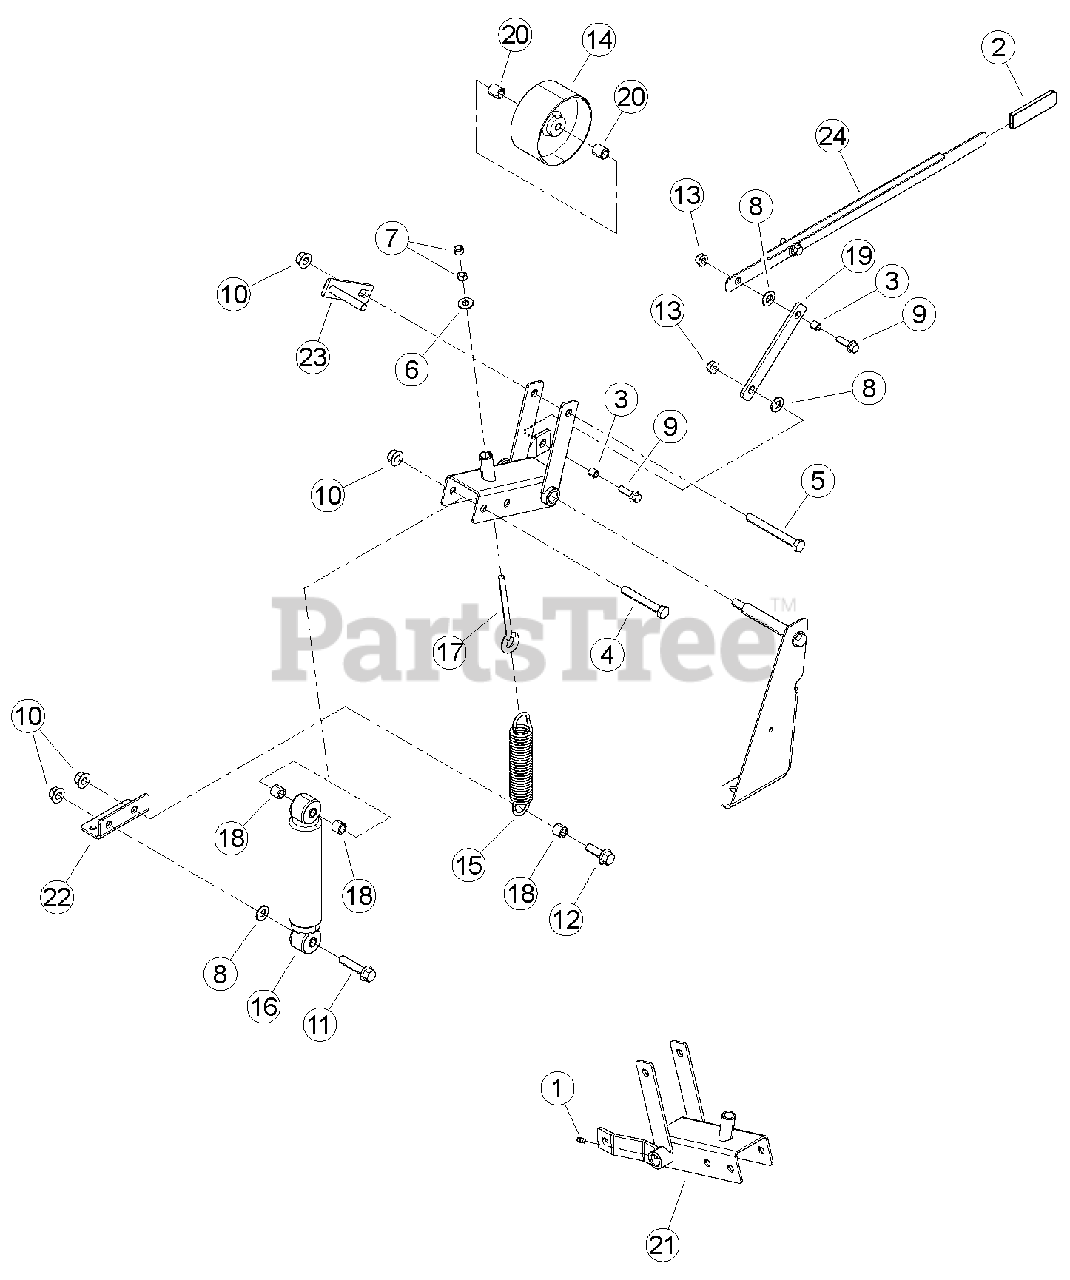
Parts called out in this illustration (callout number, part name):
1	FITTING, 1/4 SELF-TAP GREASE
2	GRIP, CLUTCH HANDLE
3	BUSHING, 3/8 X 1/2 SLEEVE LUBE
4	BOLT, 1/2 X 3-1/2" GR5 HEX HD ZP
5	BOLT, 1/2 X 4-1/2" GR5 HHCS NC ZP
6	WASHER, 3/8 FLAT
7	NUT, 3/8" HEX NC ZP
8	WASHER, 1/2 SAE FLAT
9	BOLT, 3/8 X 1-1/4 FLANGE NC
10	NUT, 1/2-13 NYLOCK FLANGE
11	BOLT, 1/2 -13 X 2-1/4 FLANGE NC
12	BOLT, 1/2-13 X 1-1/2 GR5 FLANGE NC
13	NUT, 3/8-16 NYLOCK FLANGE
14	PULLEY, IDLER 5" X 2.50"
15	SPRING, 7-3/4" EXTENSION
16	ABSORBER, IDLER SHOCK
17	EYEBOLT, 3/8" X 5" LG 4-1/4 THD ZP
18	SPACER, 0.75 X 0.620
19	LINK, ENGAGEMENT ARM
20	SPACER, IDLER SHEAVE
21	WELDMENT, IDLER ARM
22	BRACKET, SPRING ANCHOR
23	WELDMENT, BELT PIN
24	LEVER, CLUTCH ENGAGEMENT
